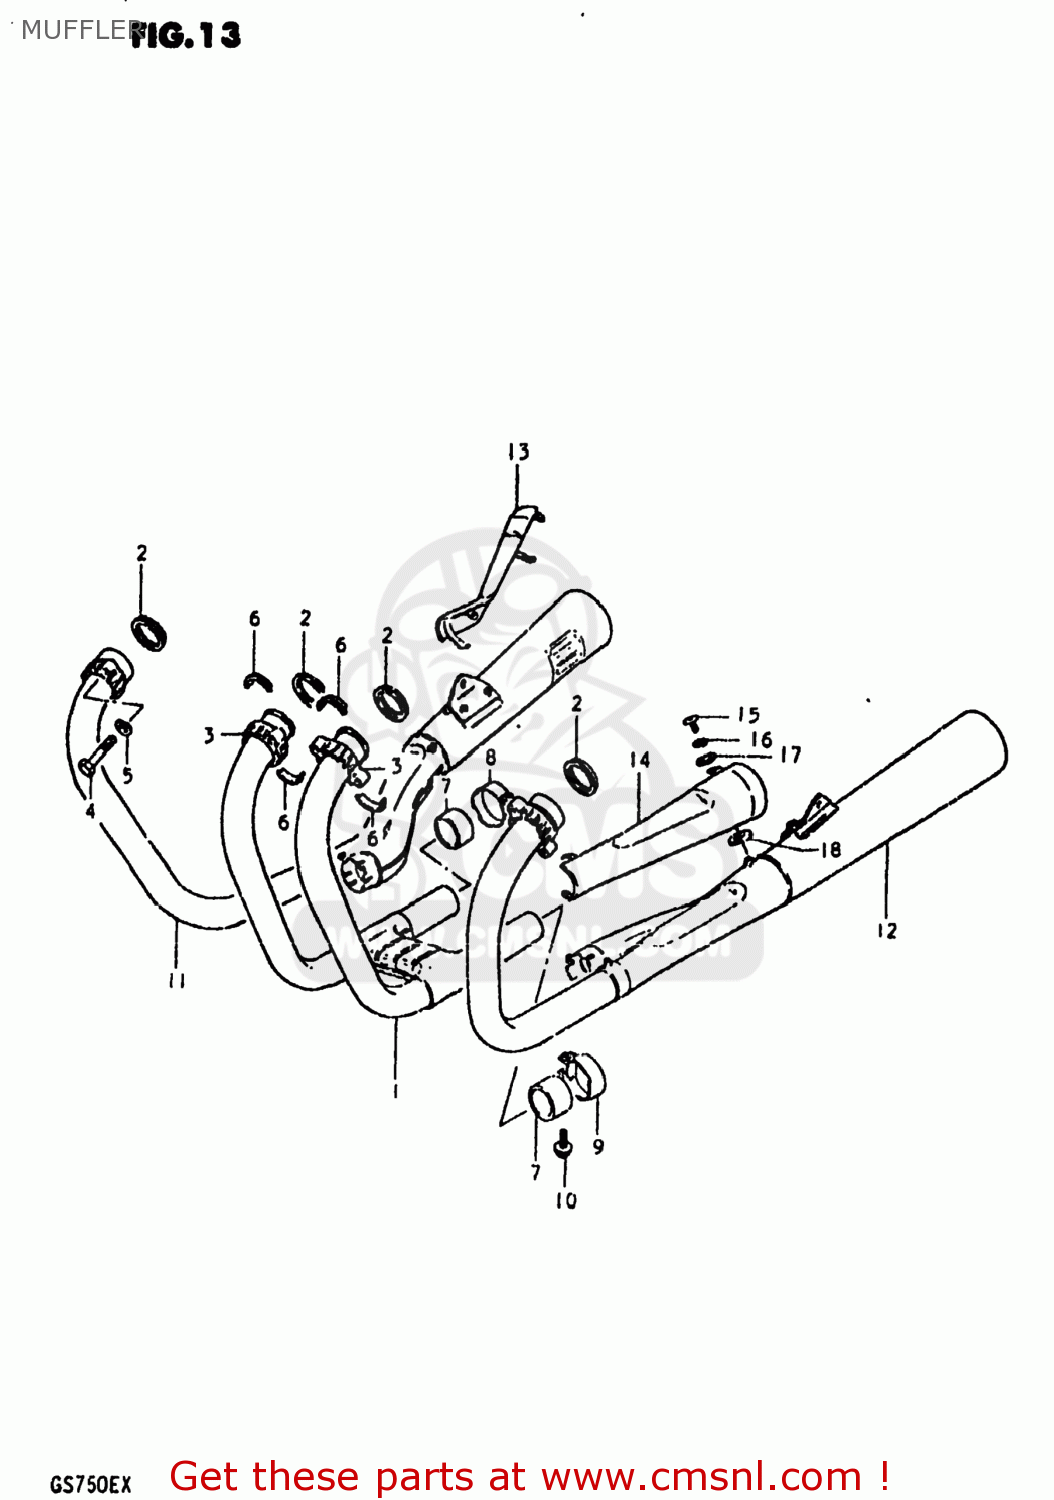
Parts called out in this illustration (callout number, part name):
1	PIPE,EXHAUST
2	GASKET,EXHAUST PIPE (NAS)
3	CLAMP,EXHAUST PIPE
4	BOLT
5	LOCK WASHER
6	PLATE,EXHAUST
7	CONNECTOR,MUFFLER
8	CLAMP,MUFFLER CONNECTOR,R
9	CLAMP,MUFFLER CONNECTOR,L
10	BOLT
11	MUFFLER ASSEMBLY
12	MUFFLER ASSEMBLY
13	COVER,MUFFLER
14	COVER,MUFFLER
15	SCREW
16	LOCK WASHER
17	WASHER
18	GASKET 6.2X12X1.5 (MCA)
